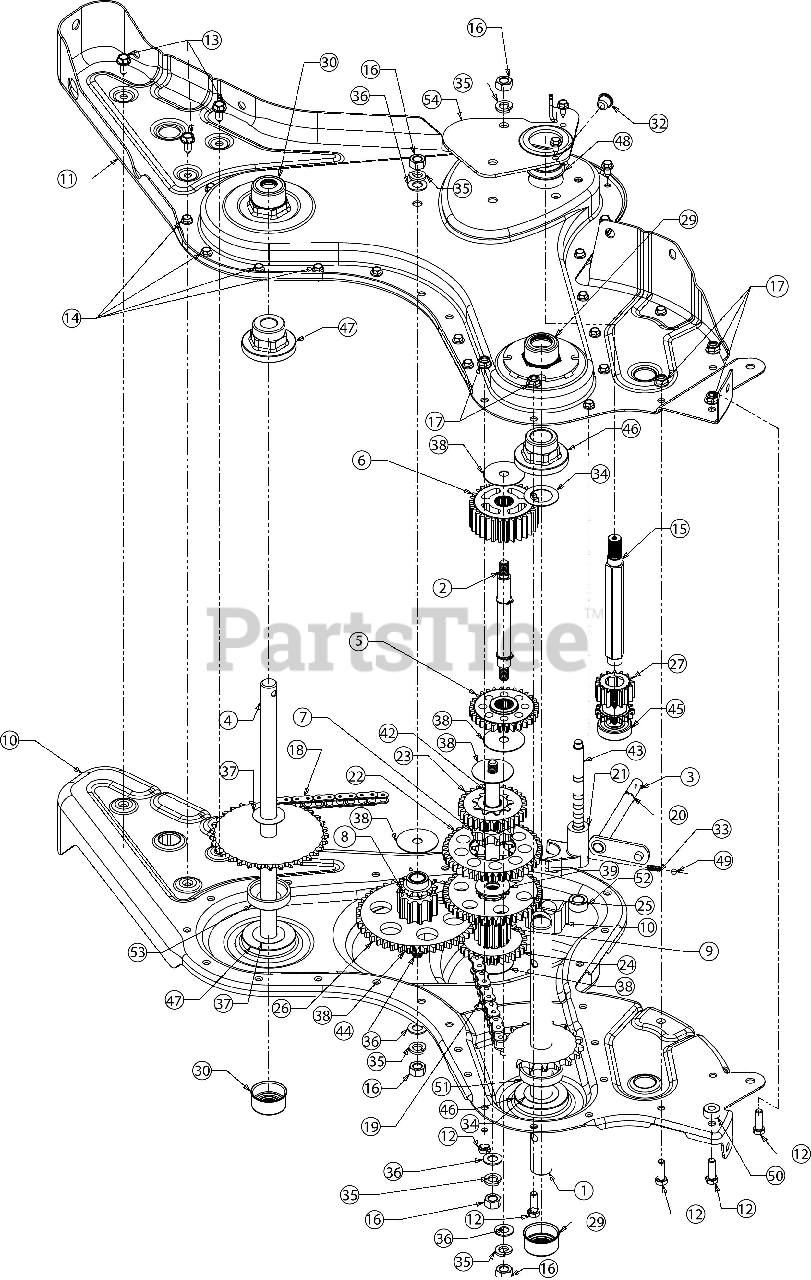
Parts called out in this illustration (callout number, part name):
1	TINE SHAFT ASSEMBLY
2	JACK SHAFT ASSEMBLY
2	RETAINING RING
2	JACK SHAFT
3	INPUT SHAFT ASSEMBLY
4	33T WHEEL SHAFT ASSEMBLY
5	30T REVERSE IDLER GEAR ASSEMBLY
5	NEEDLE BEARING
6	30T FORWARD IDLER GEAR ASSEMBLY
6	NEEDLE BEARING
7	9T TINE INPUT SPROCKET ASSEMBLY
7	NEEDLE BEARING
8	10T WHEEL INPUT SPROCKET ASSEMBLY
8	SLEEVE BEARING
9	11T GEAR ASSEMBLY
9	NEEDLE BEARING
10	CHAIN CASE HOUSING (RH)
11	CHAIN CASE HOUSING ASSEMBLY (LH)
12	SCREW 5/16-18 x 1.0 GR5
13	SCREW 5/16-18 x .750
14	SCREW 1/4-20X.625
15	INPUT SHAFT
16	HEX NUT 7/16-20
17	FLANGE LOCK NUT 5/16-18
18	#420 CHAIN-1/2 PITCH
19	CHAIN-54 LINKS 5
20	SNAP RING FOR .500
21	CLUTCH COLLAR
22	SPUR GEAR 44T
23	SPUR GEAR 30T
24	SPUR GEAR 30T
25	SPUR GEAR 44T
26	SPUR GEAR 44T
27	SPUR GEAR 16T
29	SHAFT SEAL
30	SHAFT SEAL
32	TAPER CAP PLUG
33	COMPRESSION SPRING
34	FLAT WASHER
35	LOCK WASHER 7/16
36	FLAT WASHER.469 ID x .88 OD
37	THRUST WASHER
38	THRUST WASHER
39	FLAT WASHER .635X1.585X.062 HDN
42	JACK SHAFT-.625 x 5.00 x 7/16-20
43	DETENT SHAFT
44	JACKSHAFT
45	BALL BEARING
46	BEARING
48	BALL BEARING
49	DETENT BALL
52	SPACER-.505 1D
54	GEAR POSITIONER BRACKET
